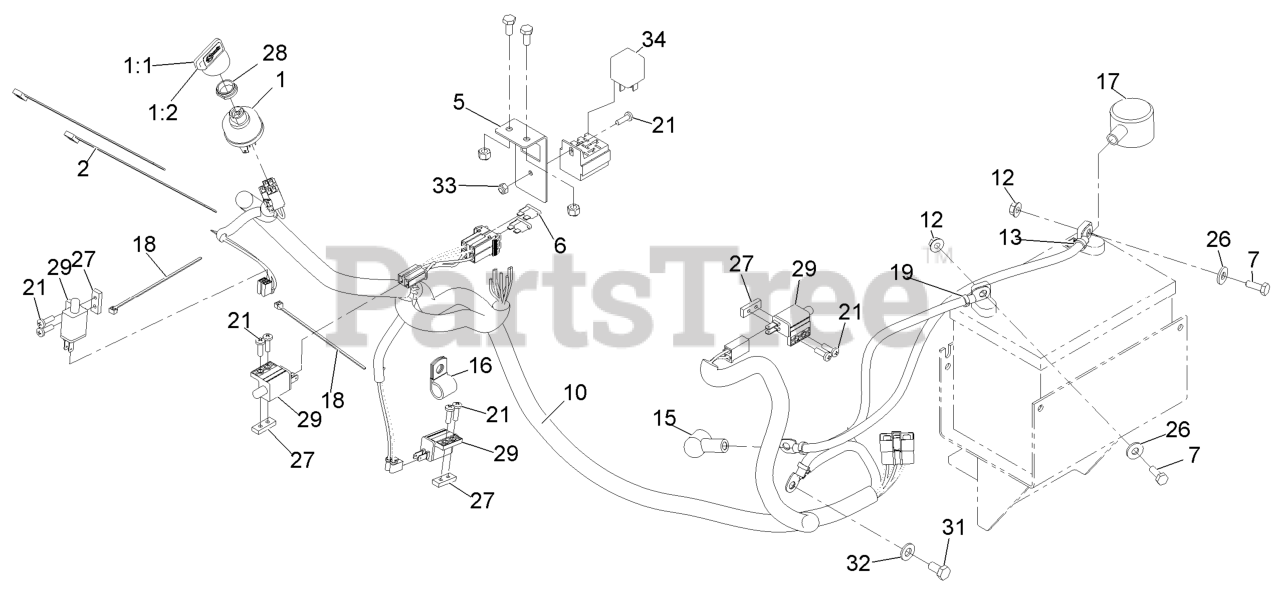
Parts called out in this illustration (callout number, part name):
1:1	KEYS-IGNITION (SPARE PAIR
1:2	KEY-IGNITION
2	TIE-PLASTIC
5	BRACKET-FUSE AND RELAY
6	FUSE-BLADE TYPE, 20 AMP
7	SCREW-HH
10	HARNESS-WIRE, TTS
13	ASM,POSITIVE BATTERY CABL
15	INSULATOR-SOLENOID
16	CLIP-LOOM
17	INSULATOR-BATTERY
18	TIE-CABLE
19	CABLE-BATTERY, NEGATIVE
21	SCREW-PPH
26	WASHER-FLAT
27	PLATE-TAPPED
28	NUT-SWITCH, IGNITION
29	SWITCH-OPEN, NORMALLY
31	SCREW-HH
32	WASHER-PLAIN
33	NUT-LOCK, NI
